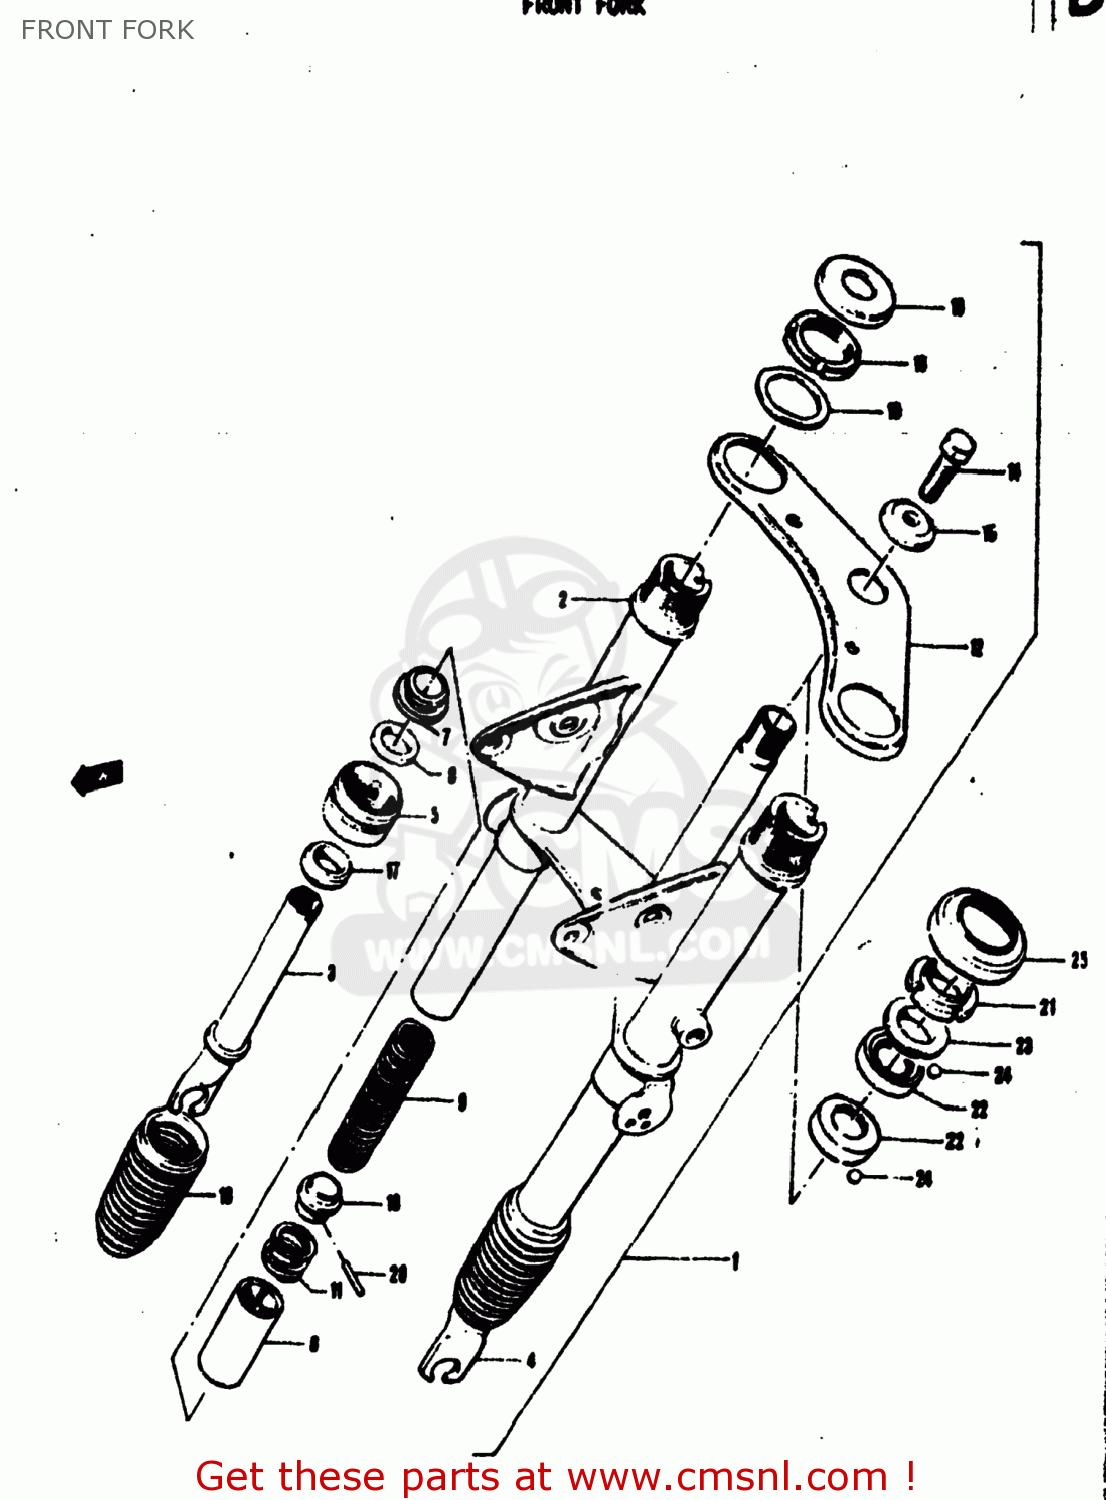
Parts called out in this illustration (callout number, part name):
5	SPRING,FRONT FORK
7	VALVE,OIL LOCK
8	OIL SEAL (22.2X30X5)
10	GUIDE,SPRING
17	CUSHION
18	BOOT
20	PIN,SPRING(4.5X22)
21	NUT,STEERING
22	RACE,STEERING,INNER,UPPER
23	LACE,STEERING OUTER UPR
24	BALL
25	COVER,STEERING,UPPER
